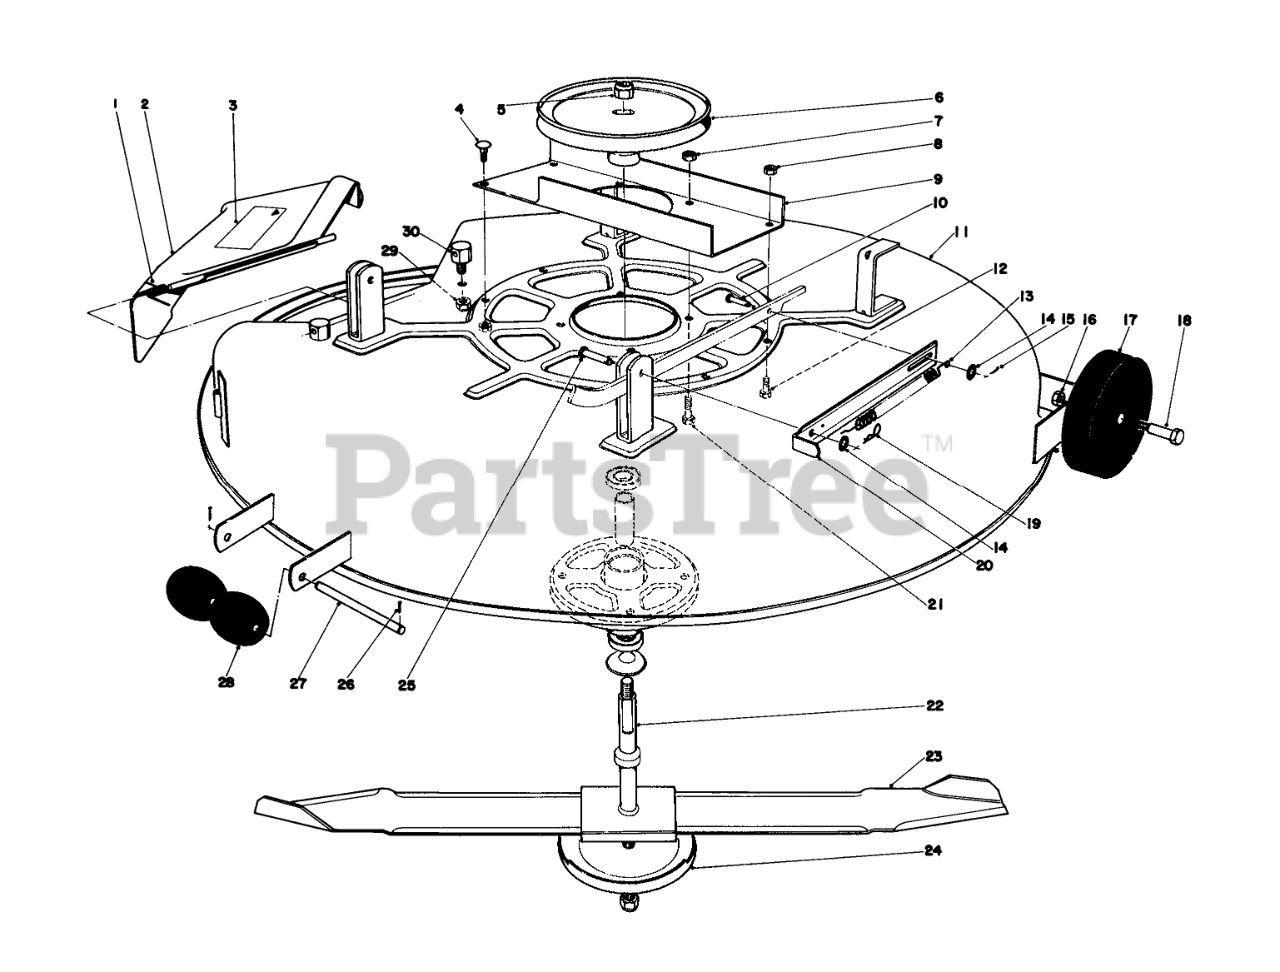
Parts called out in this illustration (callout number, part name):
1	SPRING
2	Deflector Assy. (Incl. Ref. #3)
3	Decal
4	SCREW-CARR
6	PULLEY(BLADE DRIVE)
7	NUT-LOCK, CONE
8	NUT-HEX, SIDE DEFORM
9	REINFORCEMENT CHANNEL
10	PIN-CLEVIS
11	Cutter Deck
12	SCREW-HH
13	DECK TENSION SPRNG O
14	WASHER-FLAT
15	PIN-COTTER
16	Nut
17	DECK WHEEL
19	PIN-COTTER
20	Strap-Deck Spring
21	SCREW-HH
22	Spindle Assembly
23	Blade
24	Cup
25	PIN-CLEVIS
26	PIN-COTTER
27	ROLLER SHAFT
28	ROLLER
29	NUT-LOCK, SIDE
30	POST-PIVOT
